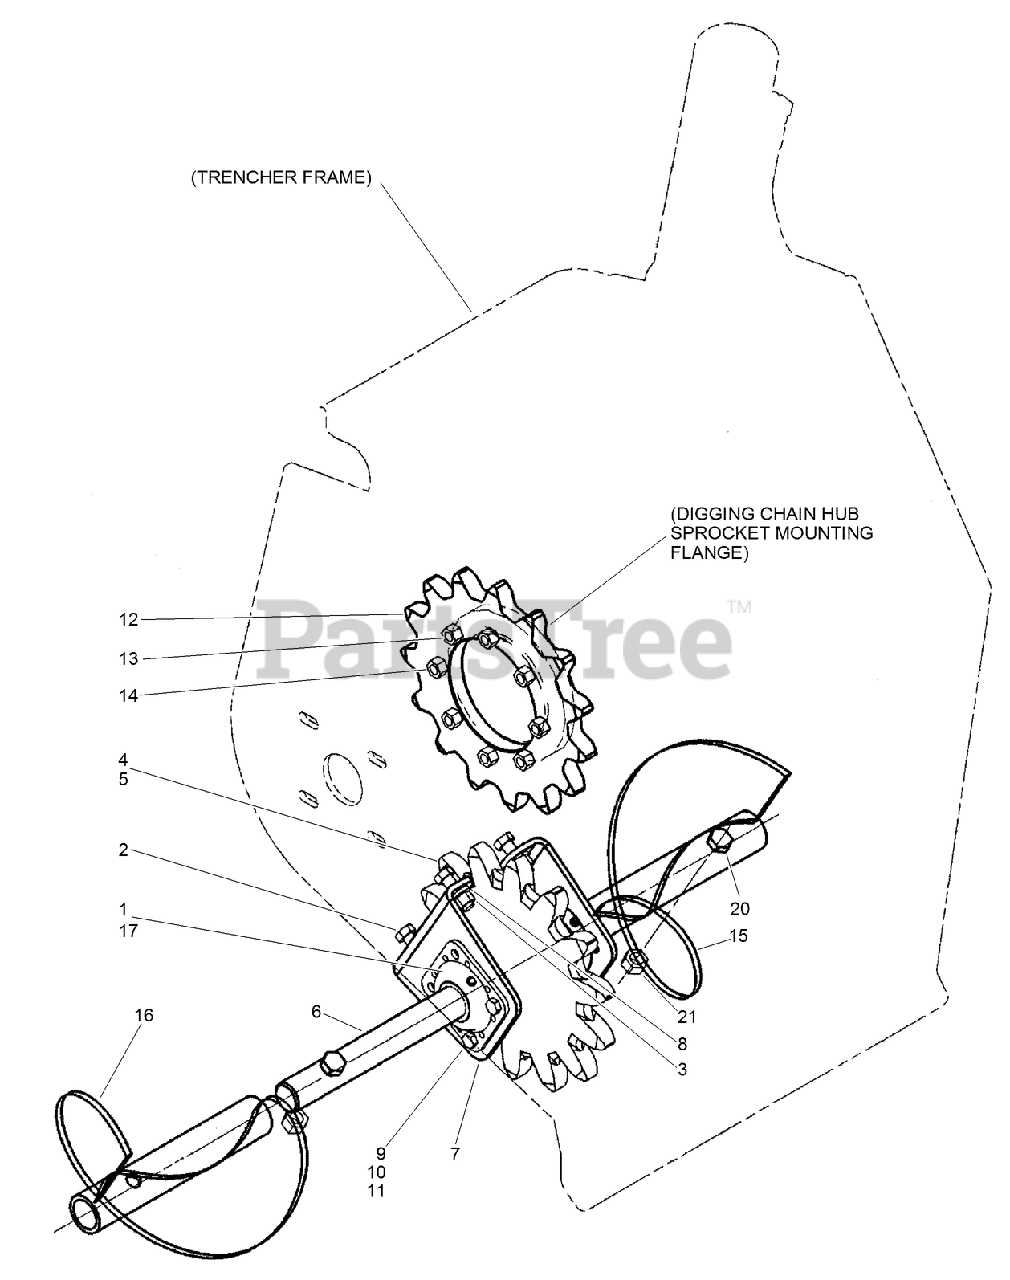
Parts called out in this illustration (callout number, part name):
1	BEARING
2	BOLT-Hex Hd 0.625 x 2.00 GR8 ZND
3	NUT-LOCK, HEX
4	SPROCKET-auger drive, 14 teeth
5	KEY-SQUARE
6	SHAFT-auger
7	PLATE-mounting, auger bearing
8	WASHER-FLAT
9	BOLT-Hex Hd 1/2 x 1-1/4 GR5 ZND
11	NUT-HEX
12	SPROCKET-Split 50/75K
13	SCREW-HH
14	NUT-Hex, 1/2 NF
15	AUGER-spoil removal, left-hand
16	AUGER-spoil removal, right-hand
20	BOLT-hex, 3/4 NC x 3 inch, grade 8
21	NUT-Prev Trq 3/4 GRC CAD Direct
